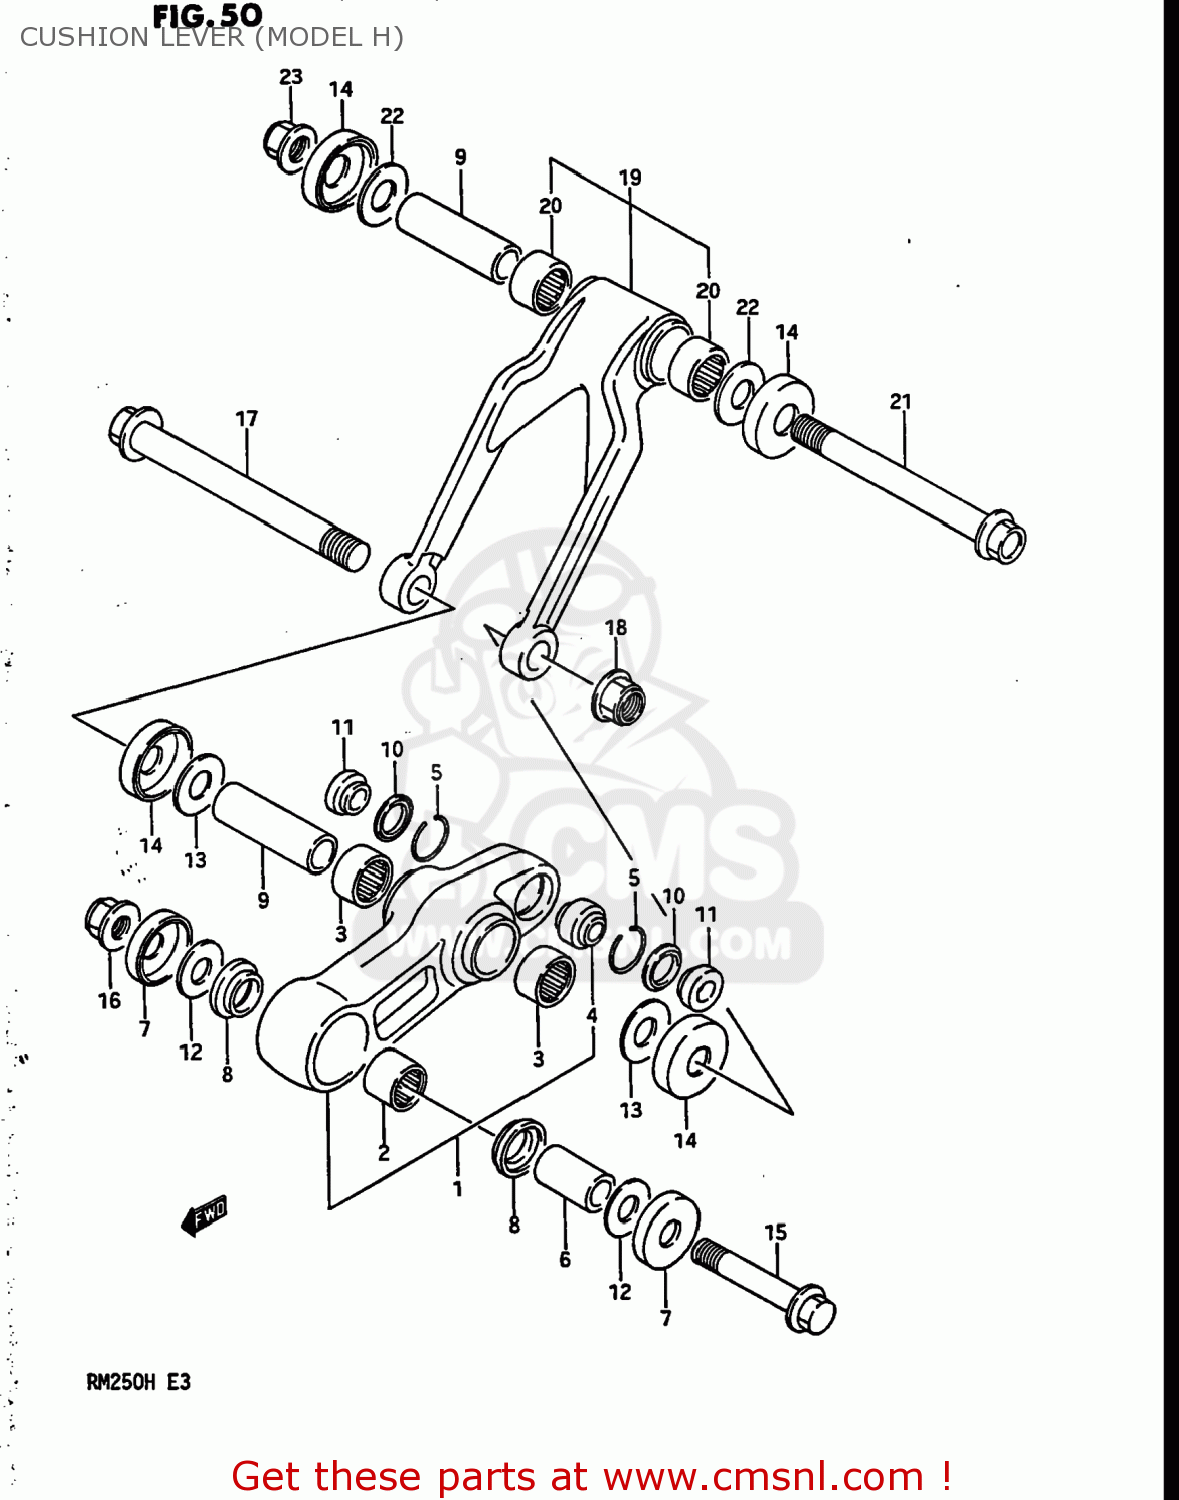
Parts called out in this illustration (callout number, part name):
1	LEVER SET,REAR CUSHION
2	BEARING(20X27X25)
3	BEARING(20X27X20)
4	BEARING,RR CUSHION LEVER
5	RING
6	SPACER,REAR CUSHION LEVER
7	COVER,REAR SWING ARM DUST
8	COLLAR,RR CUSHION LEVER FR
9	SPACER,REAR CUSHION LEVER
10	SEAL,DUST RR SHOCK ABSORBER
11	COLLAR
12	WASHER
13	WASHER
14	DUST SEAL,RR C
15	BOLT,RR CUSHION LEVER FR
16	NUT 12MM
17	SHAFT,RR CUSHION LEVER
18	NUT
19	LEVER SET,REAR CUSHION
20	BEARING(20X27X20)
21	BOLT,REAR CUSHION ROD
22	WASHER
23	NUT
